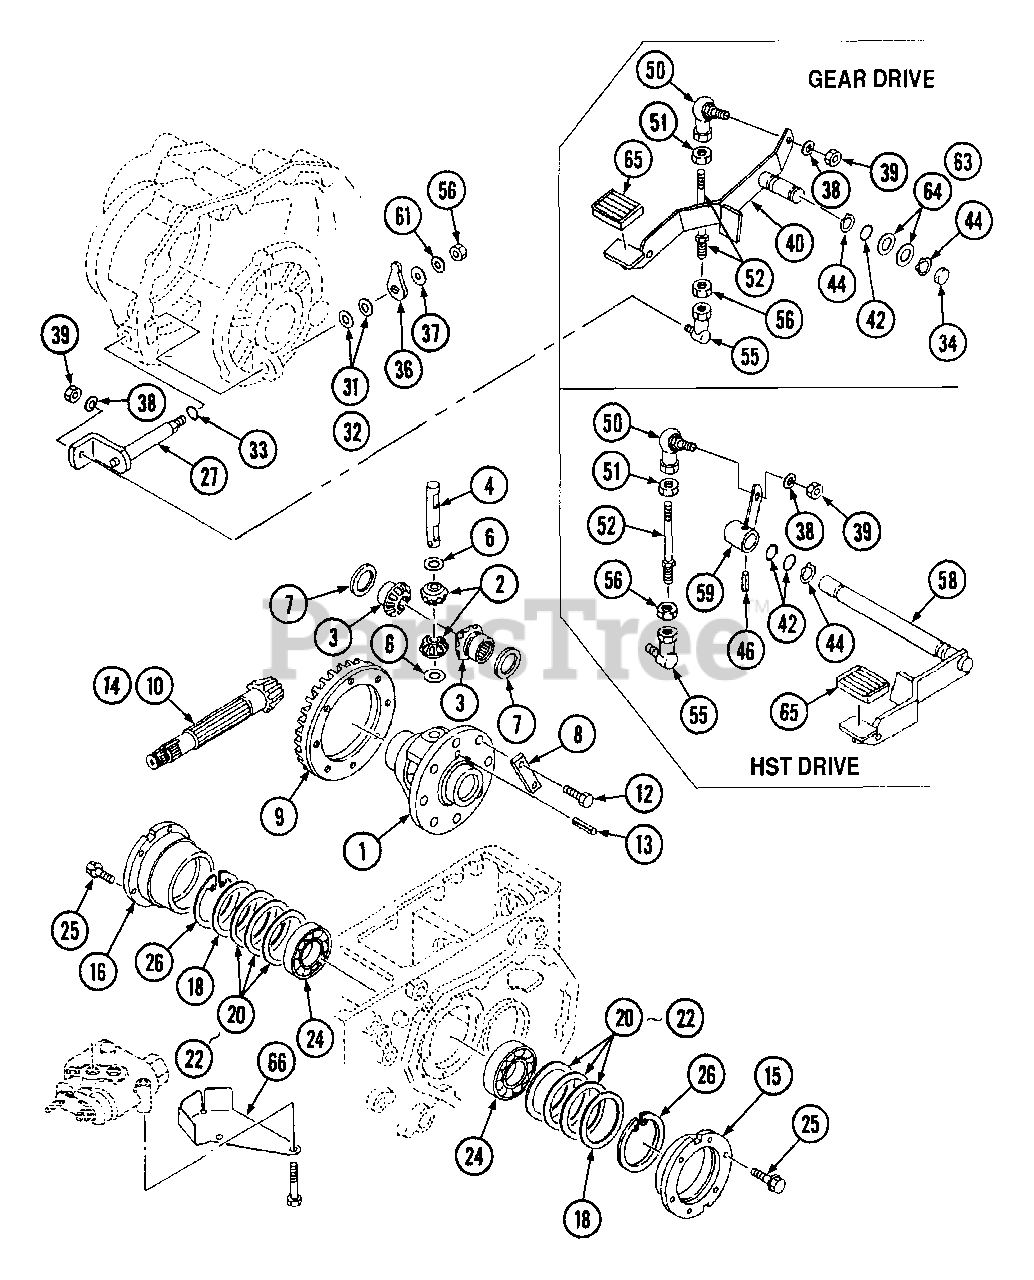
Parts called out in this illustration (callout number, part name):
1	Case, Differential
2	Pinion, Diff.
4	Shaft, Pinion
6	Washer, Thrust
7	Washer, Thrust
9	7-35 Ring Gear/Pinion Set
12	Bolt, M10-1.50
14	7-35 Ring Gear/Pinion Set
33	O-Ring
34	Seal Cap
40	Pedal, Diff. Lock
50	Ball Joint, Left Hand Thread
51	Nut, Left Hand Thread
58	Pedal, Diff. Lock
